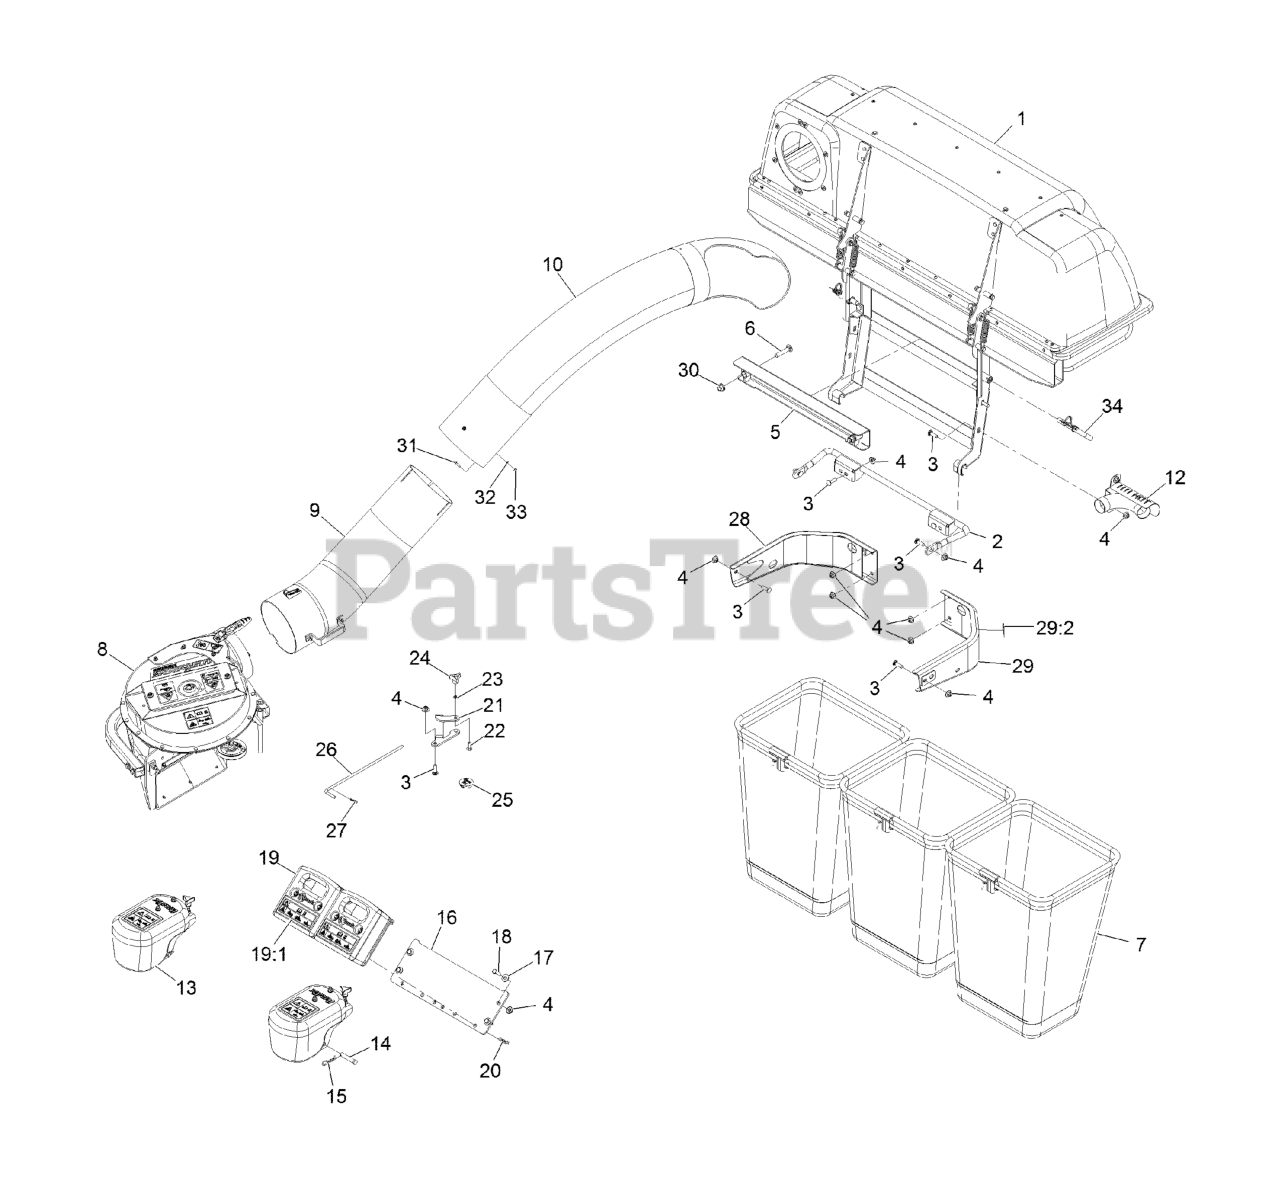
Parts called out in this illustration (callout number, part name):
1	ASM,Hood Uv 3 Bag
2	MOUNT-BAGGER, LOWER
3	Bolt-Carriage 3/8-16 X 1 1/4
4	Nut-Nyloc 3/8-16 Flg
5	MOUNT-BAGGER, UPPER
6	SCREW-CARR
7	BAG AND FRAME ASM
8	ASM, BLOWER LARGE - SVC O
9	LOWER TUBE ASM
10	TUBE-UPPER
12	EXHAUST DIVERTER ASM
13	ASM,CASTER WEIGHT
14	PIN-CLEVIS
15	PIN-COTTER
16	PLATE,WEIGHT ASM MOUNT
17	WASHER-FLAT
18	SCREW-HH
19	ASM,CAST WEIGHT
19:1	DECAL-WARNING WEIGHT
20	PIN-HAIR
21	BRACKET,BELT COVER
22	BOLT-CARR
23	RING-RETAINING, BOLT
24	KNOB-3 PRONG
25	PLUG, BLACK NYLON 1.75
26	PIN,CHUTE PIVOT
27	PIN-COTTER
28	BUMPER-RH
29	LH BUMPER ASM
29:2	DECAL-WARNING
30	Nut-Lock 1/2-13
31	SCREW-HWH
32	WASHER-FLAT
33	NUT-LOCK, NI
34	PIN-MOUNT, BAGGER
